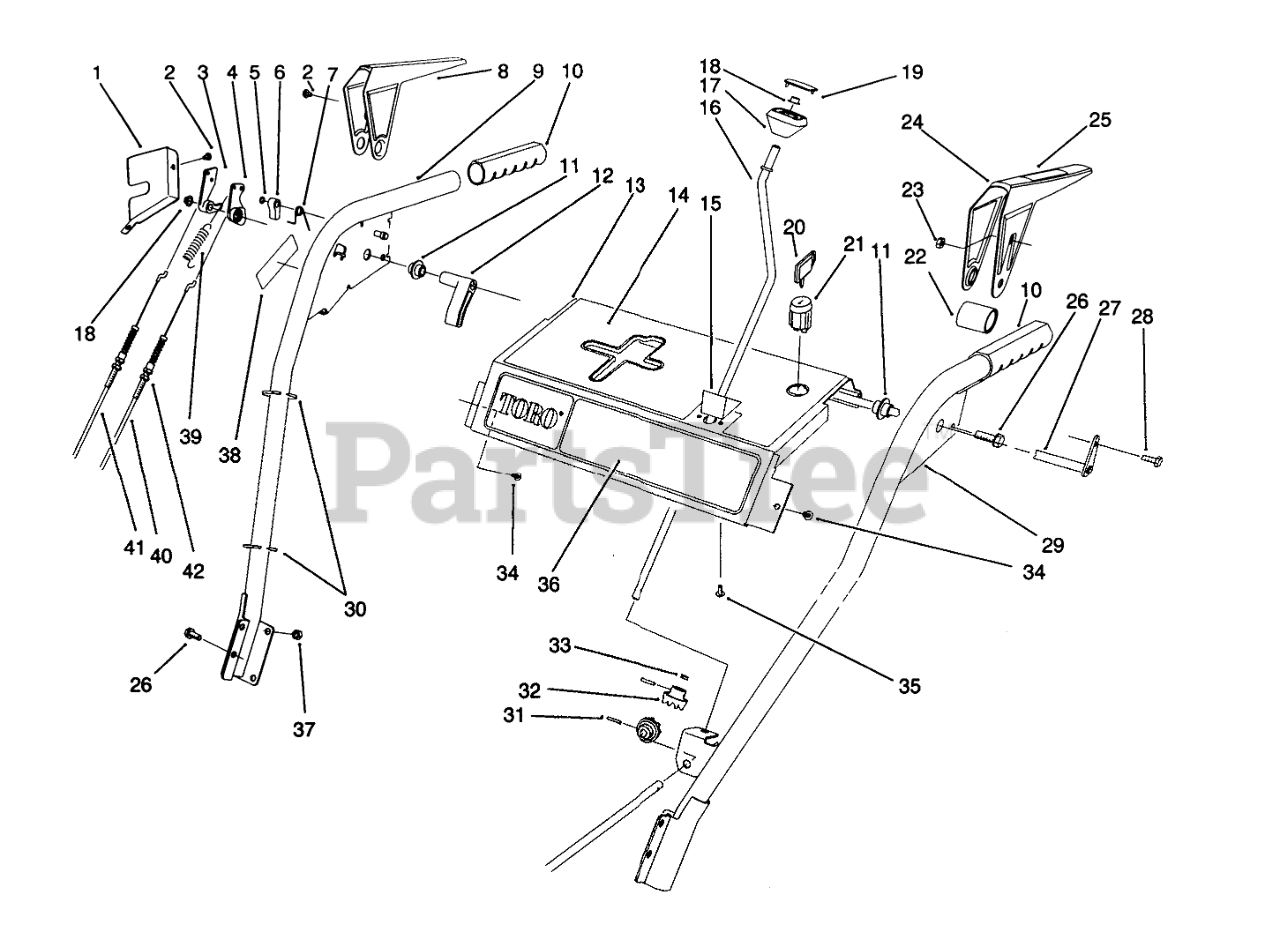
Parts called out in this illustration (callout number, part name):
1	Cover Lever Lock
2	SCREW-HH
3	TANG-LOCKING
4	CAM-RELEASE
5	E-RING-RETAINER
6	LATCH-LOCKING
7	SPRING-TORSION
8	Lever-Impeller
9	Handle-R.H.
10	GRIP-HANDLE
11	BUSHING-LEVER
12	LEVER-TRIP
13	Panel-Control
14	DECAL-TOP PANEL
15	PLATE-GUIDE
16	CRANK-ROD, CHUTE
17	KNOB-CONTROL, CHUTE
18	RETAINER-PUSH ON
19	COVER-KNOB
20	KEY-IGNITION
21	SWITCH
22	SPACER-LEVER, TRACTION
23	NUT-LOCK, NI
24	Lever-Traction
25	DECAL-LEVER
26	SCREW-HHF
27	CROSS ROD ASM
28	SCREW-HWH
29	Handle-L.H.
30	TIE-CABLE
31	PIN-SPRING
32	GEAR-UNIVERSAL
33	WASHER-RUBBER
34	SCREW-HWHTF
35	SCREW-PPH
36	DECAL-FRT PANEL (1132)
37	NUT-LOCK, NI
38	DECAL-WARNING
39	Spring-Extension
40	CABLE-TRACTION
41	CABLE-IMPELLER
42	NUT-LOCK, NI
